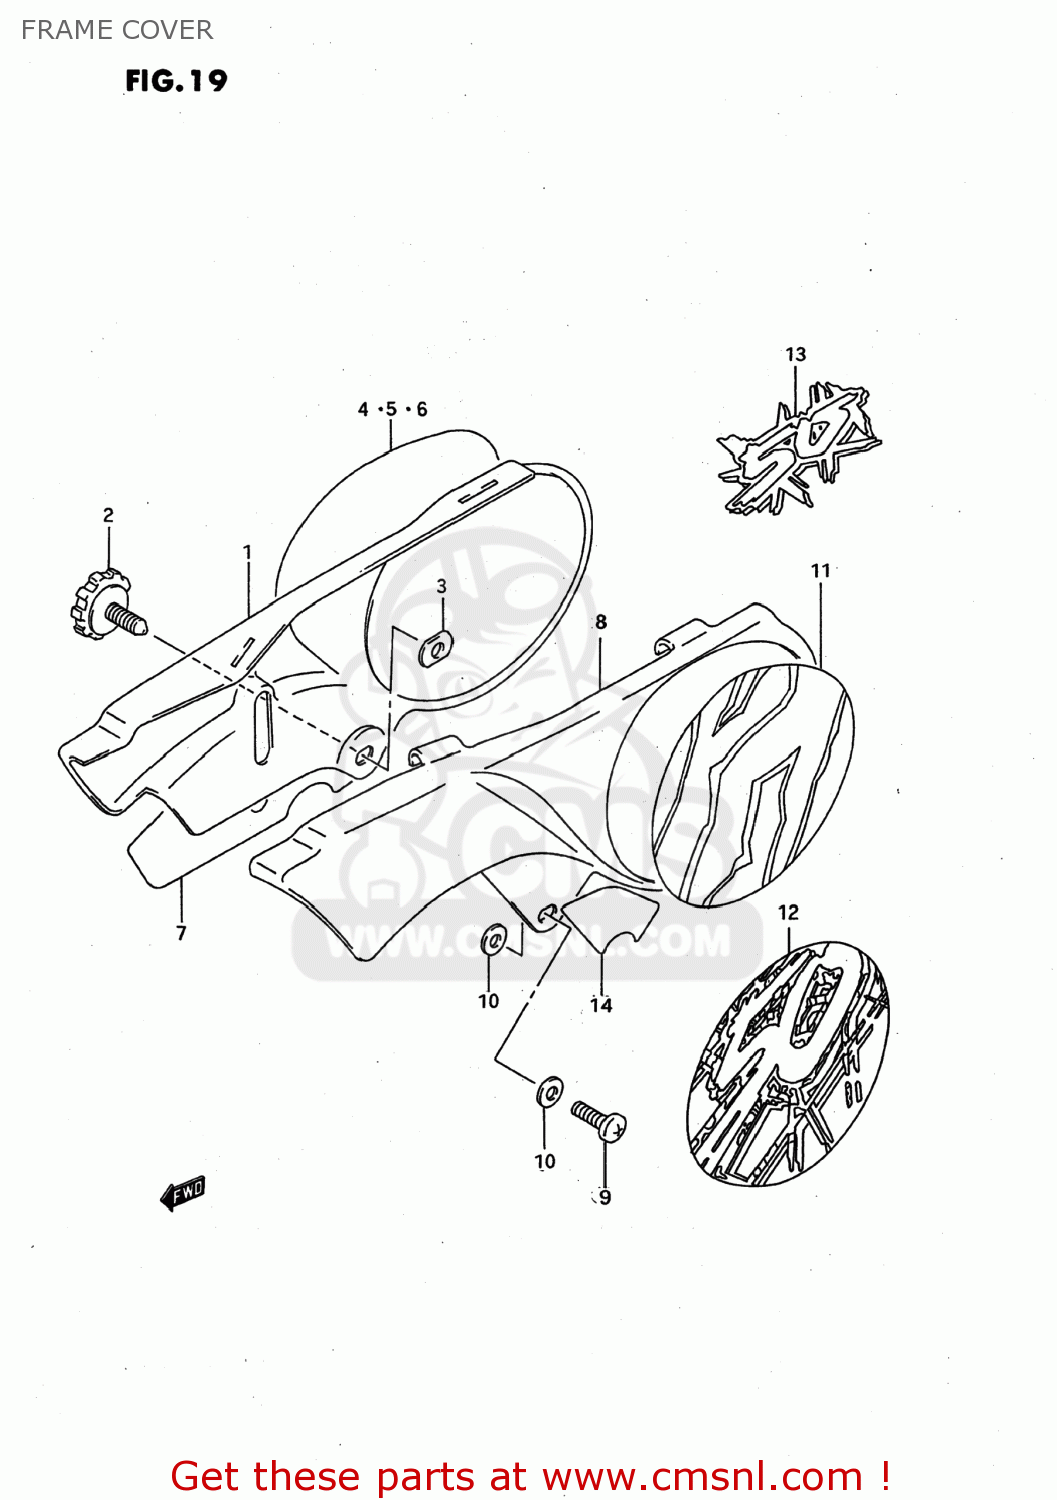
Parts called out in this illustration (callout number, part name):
1	COVER,FRAME,R(WHITE)
2	KNOB,FRAME COVER,R
3	NUT
4	TAPE,FRAME COVER,RIGHT
5	TAPE,FRAME COVER,RIGHT
6	EMBLEM,FRAME COVER
7	EMBLEM,FRAME COVER,R LWR
8	COVER,FRAME,L(WHITE)
9	SCREW
10	WASHER
11	TAPE,FRAME COVER,LEFT
12	TAPE,FRAME COVER,LEFT
13	EMBLEM,FRAME COVER
14	EMBLEM,FRAME COVER,L LWR
